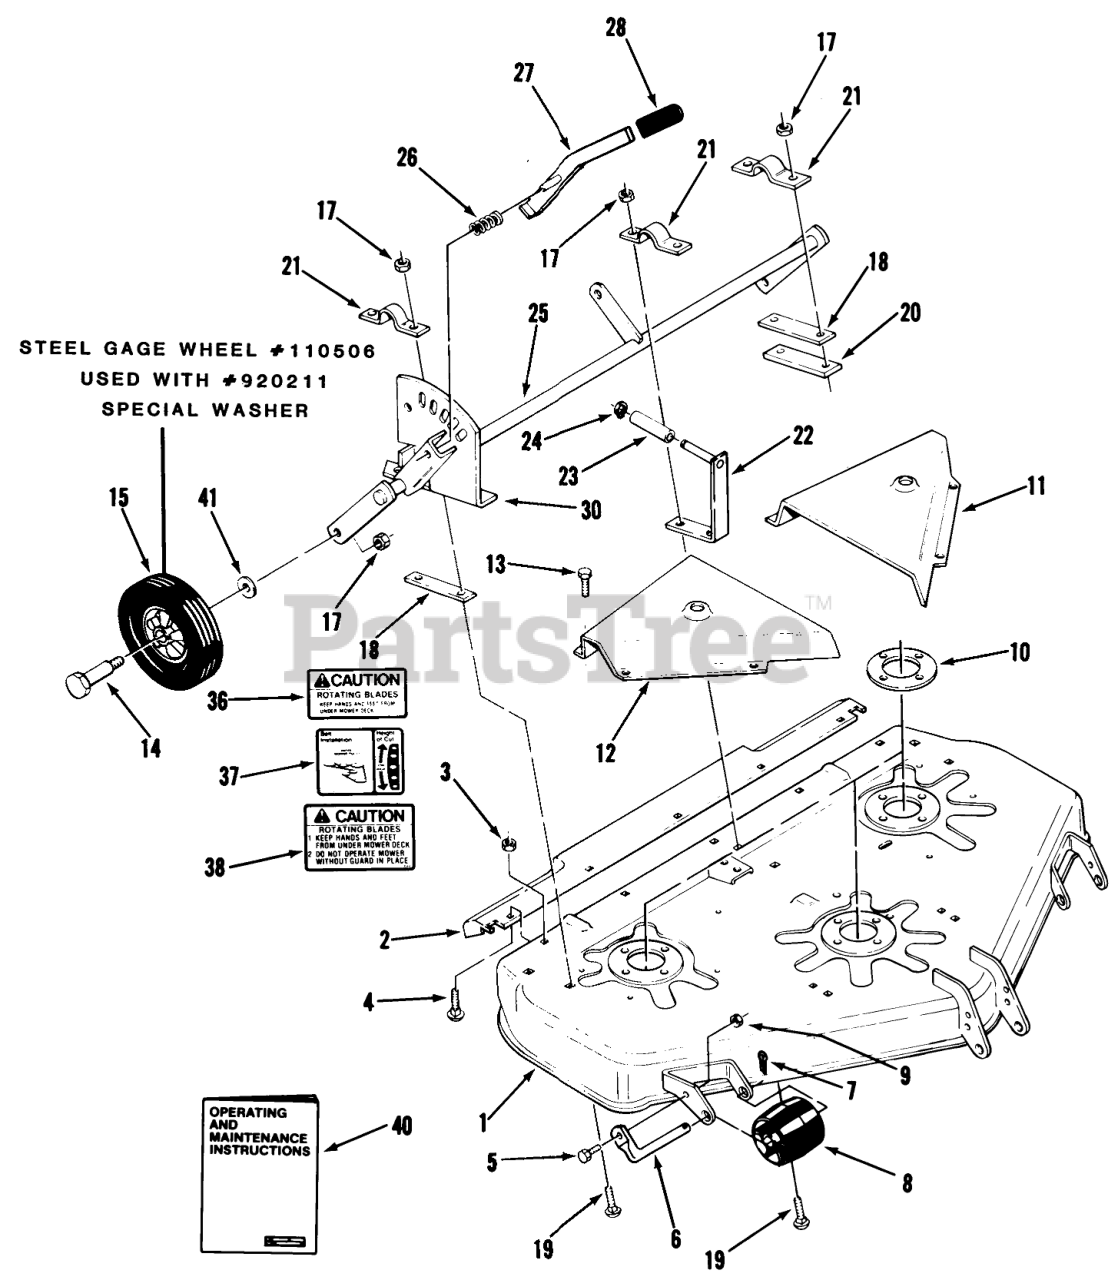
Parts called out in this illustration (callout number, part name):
1	Mower Deck
2	EXTENSION R
3	Nut
4	CARRIAGE BOLT -4
5	H H C S
6	Roller Shaft
7	Cotter Pin
8	Roller
9	Nut
10	PLATE-SPINDLE
11	Belt Cover LH
12	Belt Cover RH
13	SCREW -4
14	BOLT-SHOULDER
15	Wheel 6 x 1.75
17	Nut
18	Strap 1/16
19	Bolt
20	Strap
21	CLAMP
22	Bracket Guide
23	SPACER
24	Snap Ring
25	Gage Wheel Support
26	SPRING-COMPRESSION
27	Lever
30	Quadrant
36	Caution Decal
37	DECAL-HEIGHT BELT
38	Decal-Caution
40	Operating & Maintenance Instructions
41	WASHER
